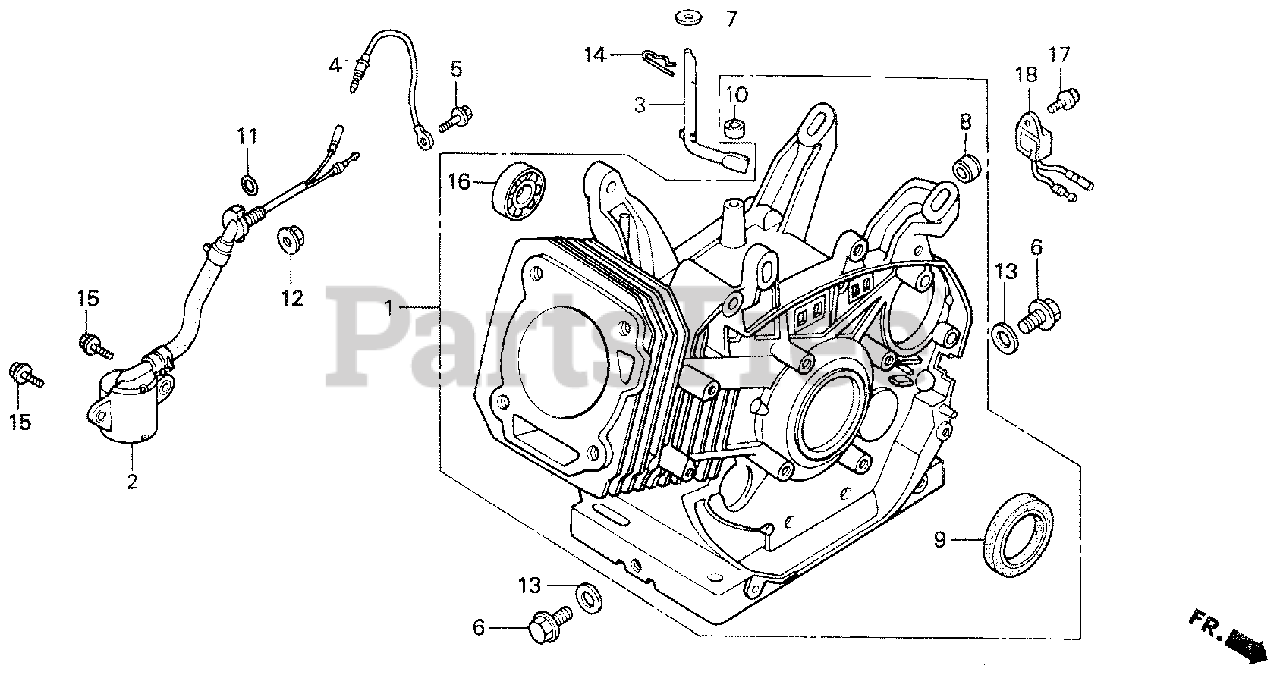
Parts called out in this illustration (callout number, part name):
1	CYLINDER ASSY.
1	CYLINDER ASSY. (ALERT)
2	SWITCH ASSY., OIL LEVEL
3	SHAFT, GOVERNOR ARM
4	SUB-HARNESS
5	BOLT, FLANGE (6X12) (CT200)
6	BOLT, DRAIN PLUG
7	WASHER (8.2X17X0.8)
9	OIL SEAL (35X52X8)
10	OIL SEAL (8X14X5)
11	O-RING (13.5X1.5) (ARAI)
12	NUT, FLANGE (10MM)
13	WASHER, DRAIN PLUG (12MM)
14	PIN, LOCK (10MM)
15	BOLT, FLANGE (6X12)
16	BEARING, RADIAL BALL (6202)
17	BOLT, FLANGE (6X12) (CT200)
18	ALERT UNIT, OIL
